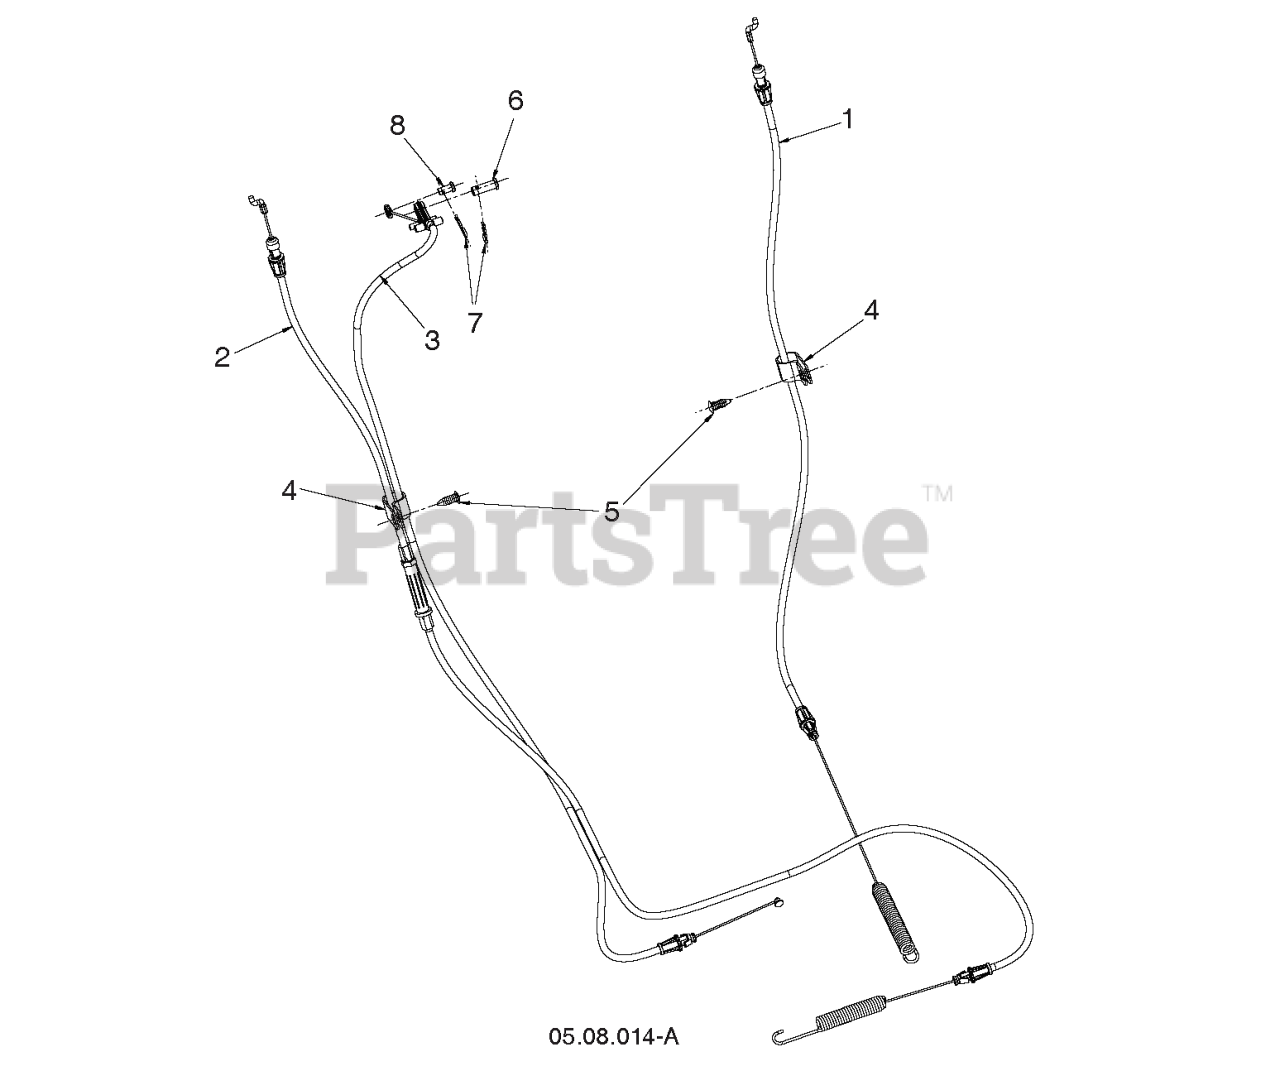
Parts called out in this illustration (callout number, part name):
1	CABLE.DRIVE CONTROL W/ADJ
2	CABLE.CONTROL.AUGER
3	CABLE.CONTROL.SPEED.DSST.OPP
4	CLIP.CABLE.BLK
5	FASTENER.PUSH.O.250X0.783
6	PIN CLEVIS 5/16X.875
7	HAIRPIN.SOFT.ZINC.059X1.125
8	PIN CLEVIS .25 X .31
